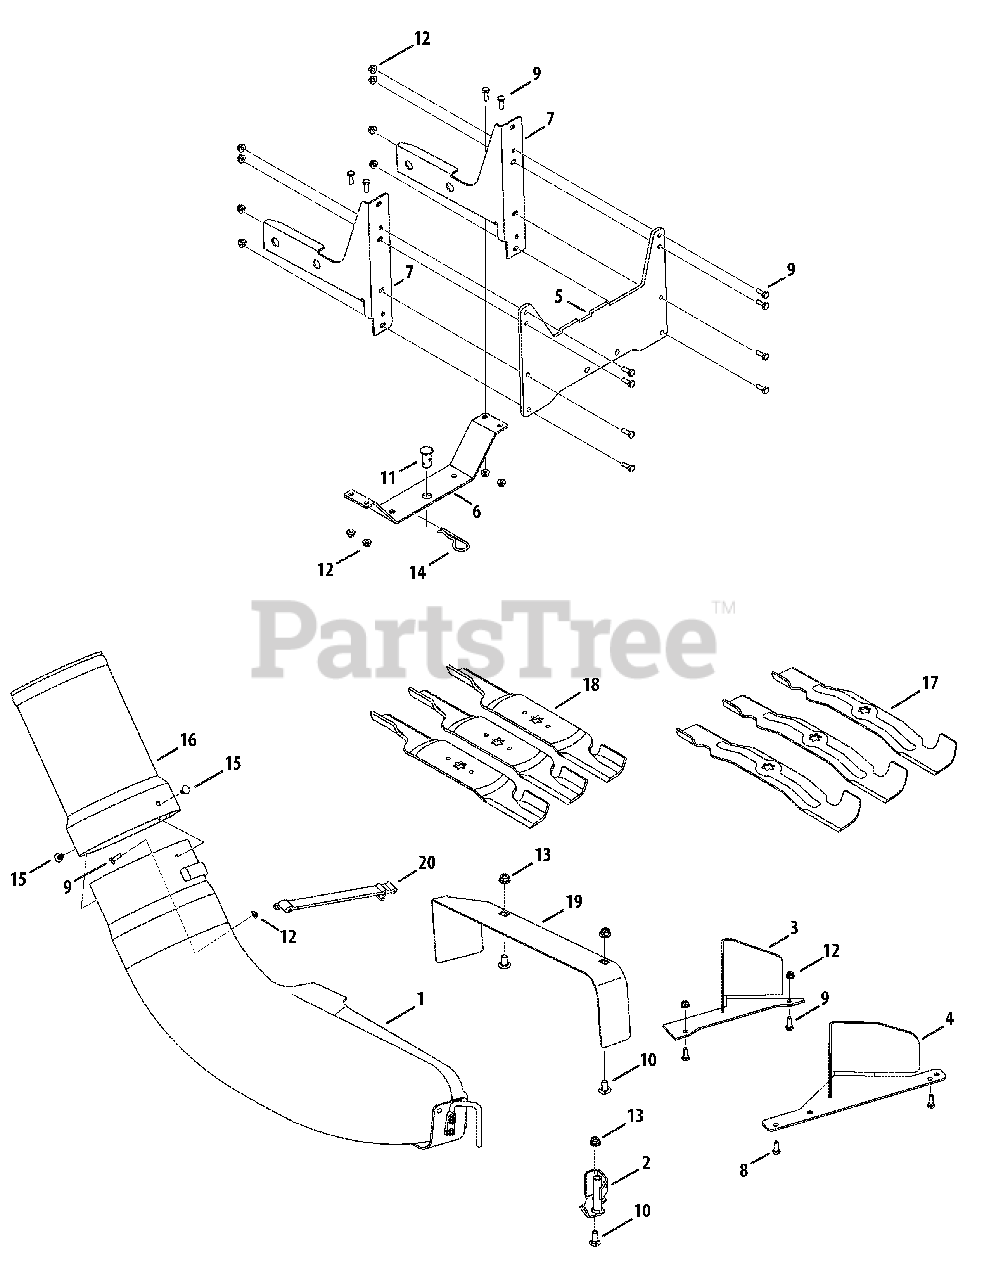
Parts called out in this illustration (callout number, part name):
1	Discharge Chute Assembly, 50" & 54"
2	Chute Stop Bracket
3	Deck Baffle, 50" Deck
4	Deck Baffle, 54" Deck
5	Bagger Mounting Plate
7	Catcher Support Bracket
8	Self-tapp Screw, 5/16-18 x .750
9	Hex Head Screw, 1/4-20 x .75
10	Carriage Bolt, 3/8-16 x 1.00
11	Clevis Pin, .62" Dia.
12	Flange Lock Nut, 1/4-20
13	Flange Lock Nut, 3/8-16
14	Internal Cotter Pin, .148 x 3.00
15	Ratchet Clip
16	Bagger Chute Adapter
17	Blades, 17.90 Bagging
18	Blades, 18.50 Extra Hi-Lift
19	Chute Discharge Plate
20	Chute Strap
